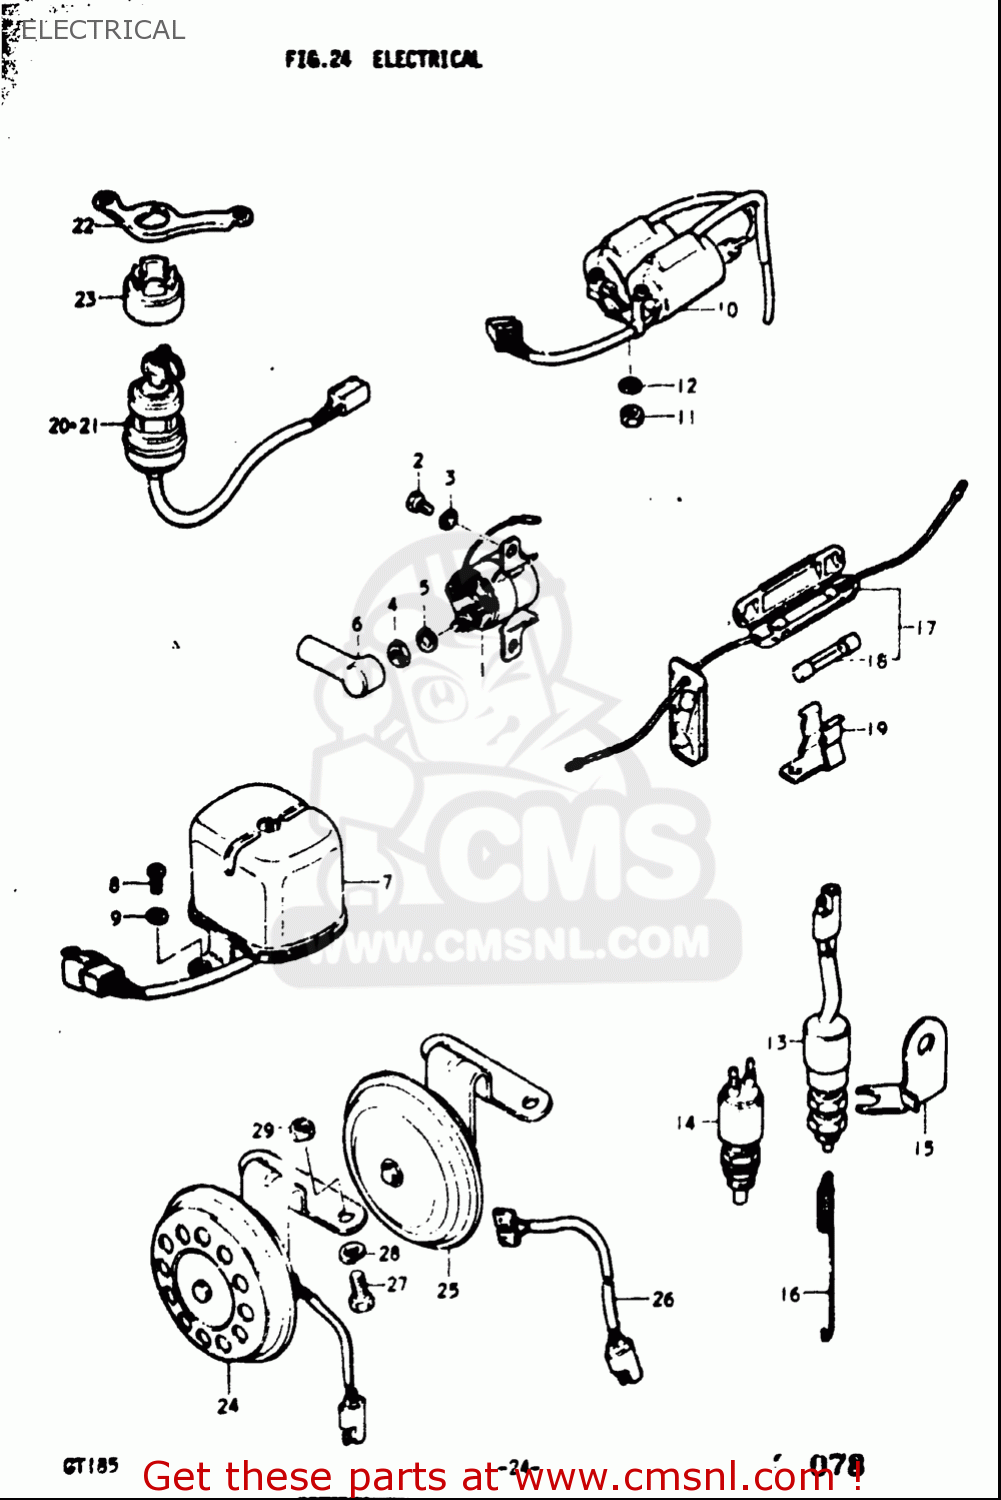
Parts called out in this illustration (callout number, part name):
1	RELAY ASSY,STARTING MOTOR
2	BOLT
3	WASHER,LOCK
4	NUT
5	WASHER,LOCK
7	REGULATOR ASSEMBLY
8	SCREW
9	WASHER,LOCK
10	COIL ASSY,IGNITION
11	NUT
12	WASHER,LOCK
14	SWITCH ASSY,BRAKE LAMP
16	SPRING
17	CASE ASSY,FUSE
18	FUSE(20A)
20	SWITCH ASSY,IGNITION
21	SWITCH ASSY,IGNITION
25	HORN ASSY
26	WIRE
27	BOLT
28	WASHER,LOCK
29	NUT
